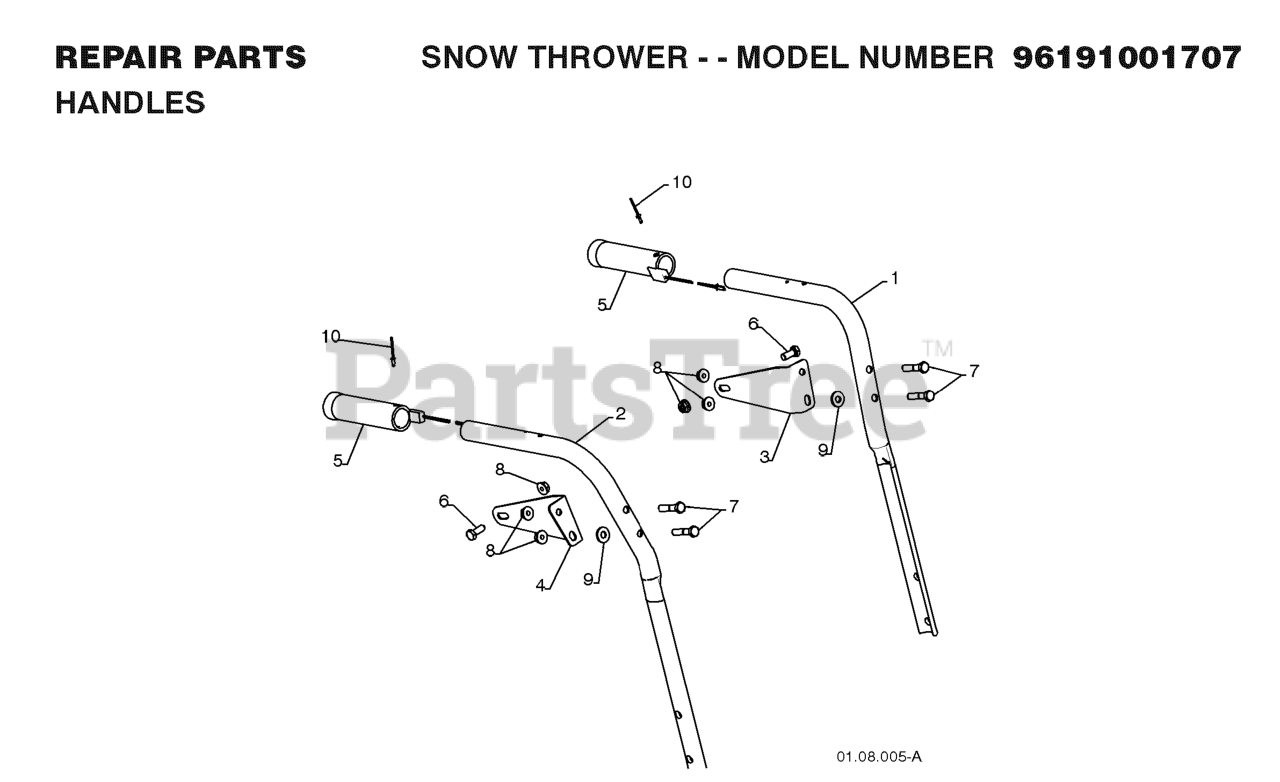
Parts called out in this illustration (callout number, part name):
1	TUBE.HANDLE.PLOW.LH.BLACK
2	TUBE.HANDLE.PLOW.RH.BLACK
3	BRKT.PANEL.LH.INT
4	BRKT.PANEL.RH.INT
5	GRIP.HANDLE.HEATED
6	BOLT.FIN.HEX.5/16-18X3/4
7	HEX BOLT
8	NUT.LOCK.5/16-18
9	WASHER.20X8.5
10	RIVET.POP.1/8X
